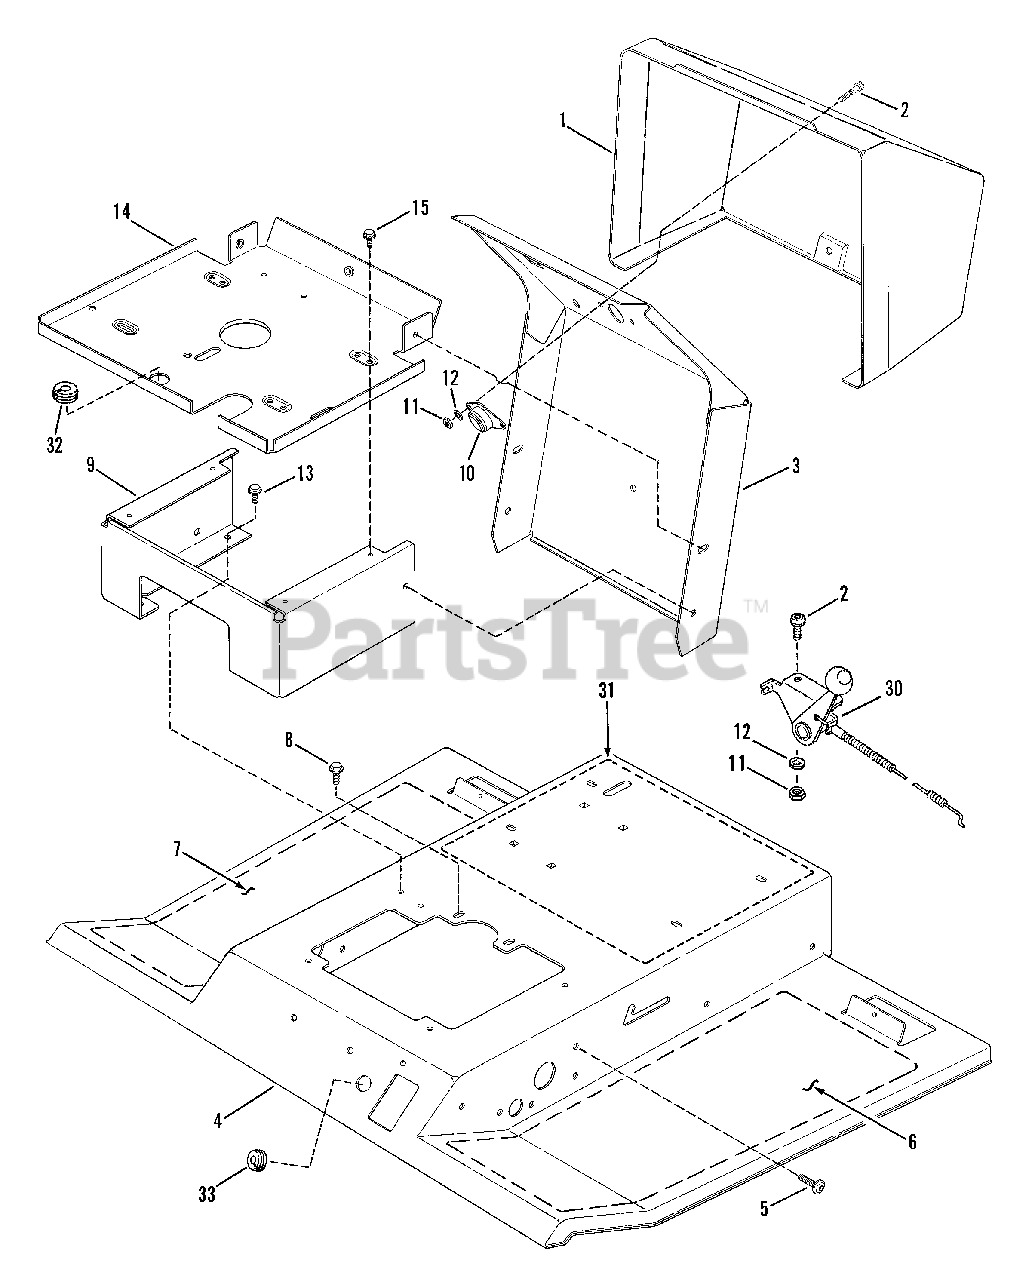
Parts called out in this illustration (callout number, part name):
1	PANEL, Dash
2	SCREW, 1/4-20x1" Phillips
3	SUPPORT, Steering Shaft
4	CHANNEL, Foot Rest
5	SCREW, 5/16-18x7/8" Torx, S.T.
6	TREAD, Left Side (Non-Skid)
7	TREAD, Right Side (Non-Skid)
8	SCREW, 5/16-18x5/8" H.C.S.T.
9	MOUNT, Fuel Tank/Battery
10	FLANGE ASSM'Y., Steering Shaft
11	NUT, 1/4-20 Hex Lock
12	WASHER, 1/4 Internal Tooth Lock
13	SCREW, 5/16-18x1/2" Self-Tapping
14	PLATE, Fuel Tank & Battery Mount
15	SCREW, 1/4-20x1/2" H.C.S.T.
30	CONTROL, Throttle
31	DECAL, Caution & Instruction
32	GROMMET, 11/16 I.D.x1-5/16" O.D. Split
33	GROMMET, 5/16 I.D.x1" O.D. Split
